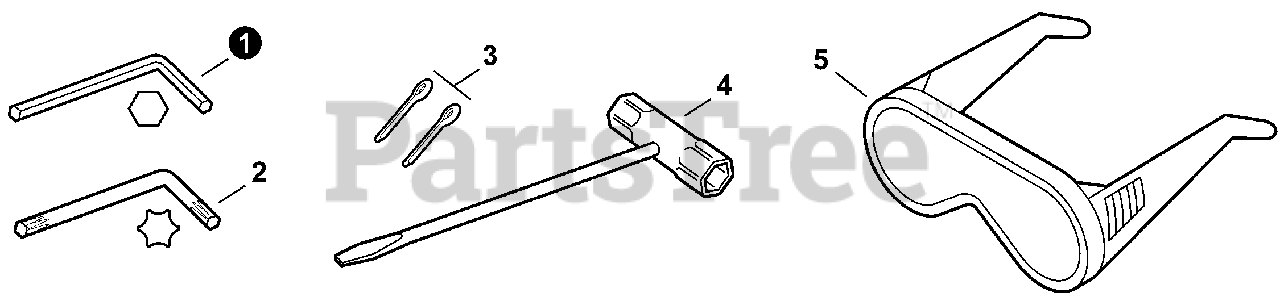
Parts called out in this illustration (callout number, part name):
1	WRENCH, ALLEN 4MM
2	WRENCH, ALLEN T27 80×30
3	PIN, COTTER 2×22
4	T-WRENCH 17×19 L200
5	GLASSES, SAFETY
